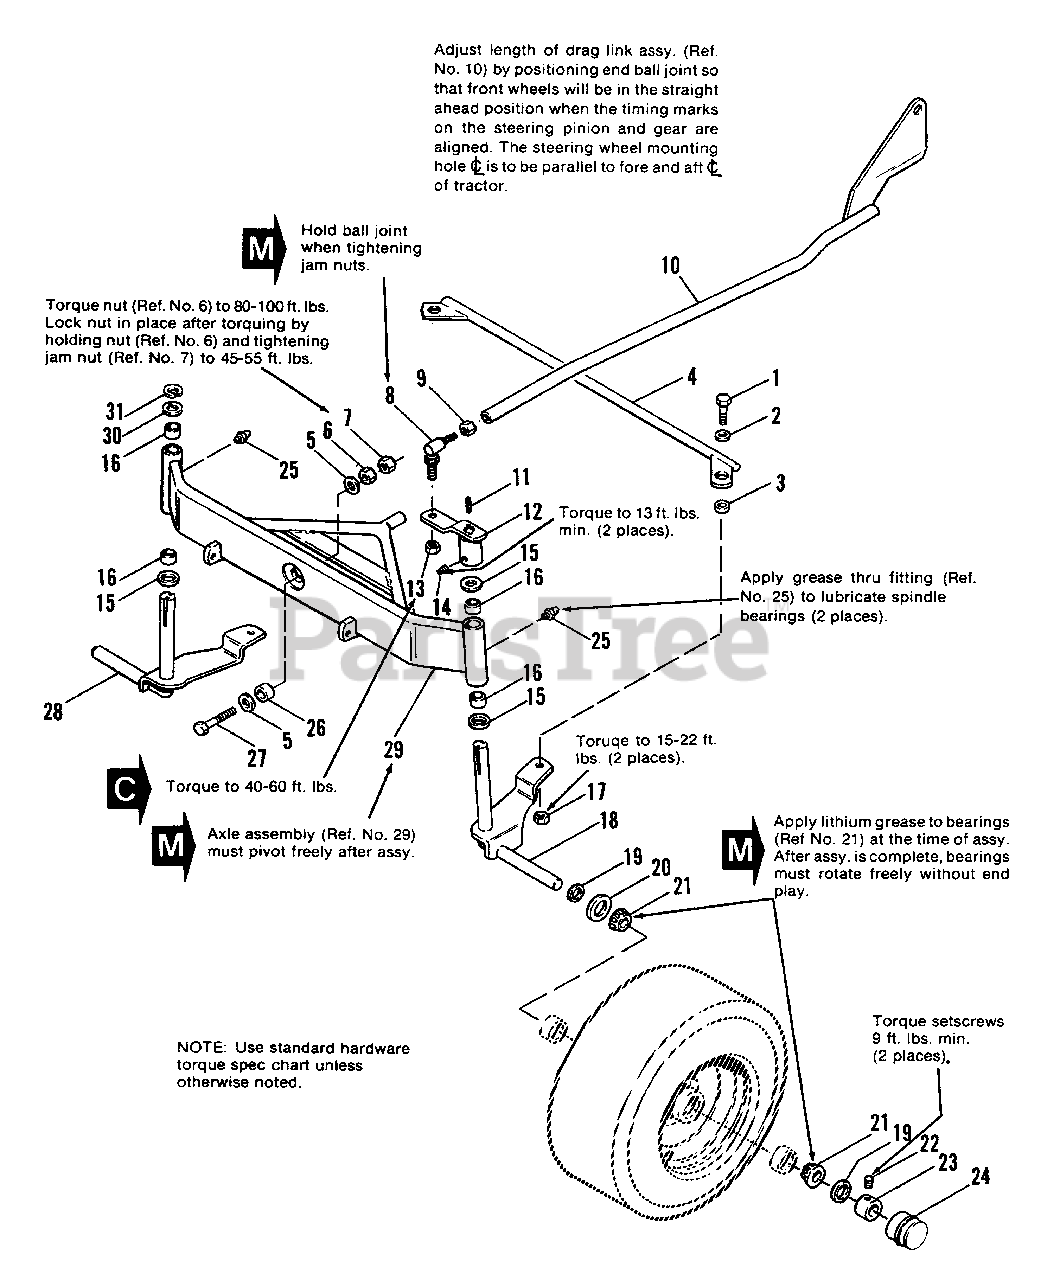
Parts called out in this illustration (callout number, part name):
1	CAPSCREW, Hex Hd., 3/8-16 x 1
2	WASHER, Plain, 3/8
4	TIE ROD ASSY.
5	WASHER, Plain, 1/2
6	LOCKNUT, Hex, 1/2-13
7	NUT, Hex, Jam, 1/2-13
8	JOINT, Ball
9	NUT, Hex, Jam, 1/2-20
10	DRAG LINK ASSY.
11	KEY, Square
12	ARM ASSY., Steering
13	LOCKNUT, Hex, 1/2-20
14	SETSCREW, Sq. Hd., 5/16-18 x 1/2
17	LOCKNUT, Hex, 3/8-16
18	SPINDLE ASSY., L.H.
21	BEARING, Cone
22	SETSCREW, Skt. Hd., 5/16-18 x 5/16
23	COLLAR, Set
24	CAP, Hub
25	FITTING, Grease
27	CAPSCREW, Hex Hd., 1/2-13 x 2-1/4
28	SPINDLE ASSY., R.H.
29	FRONT AXLE ASSY.
31	RING, Retaining
